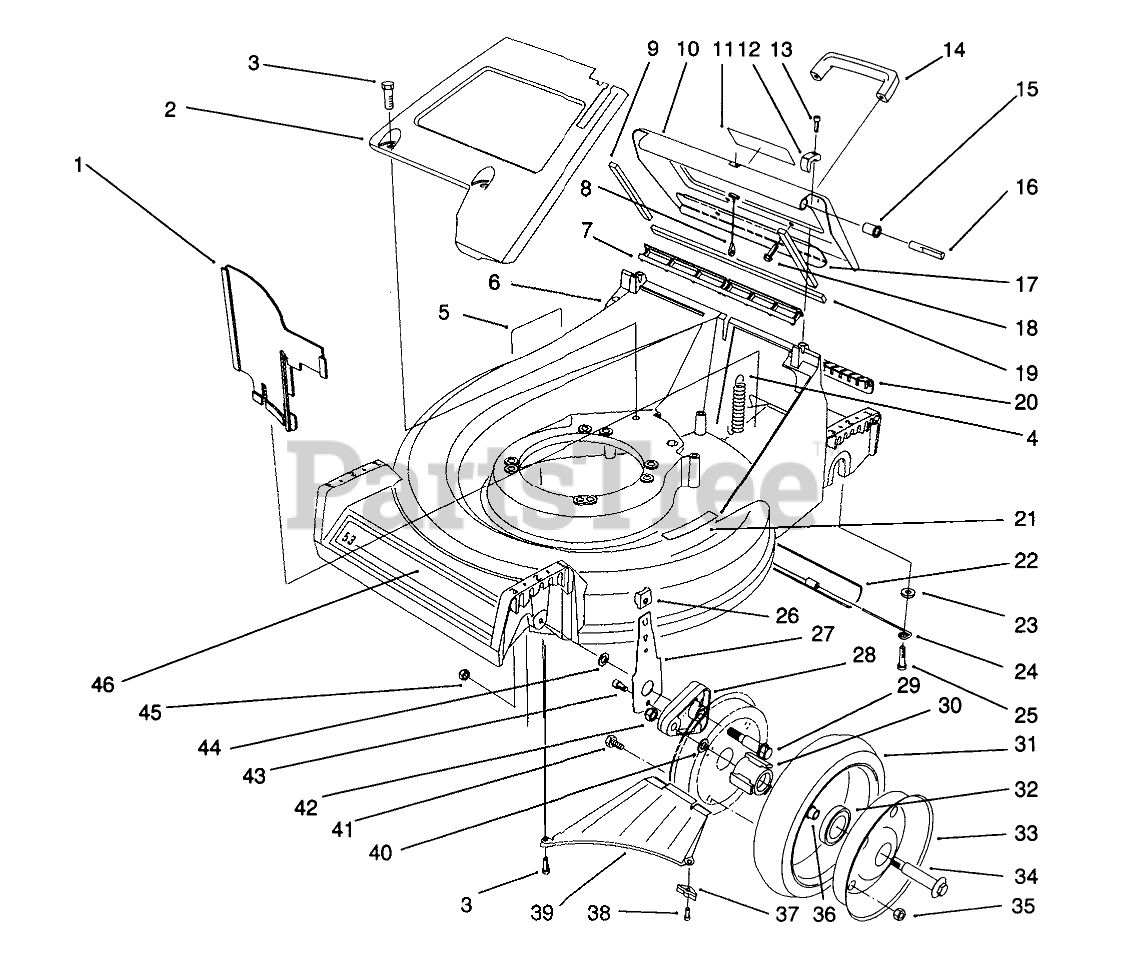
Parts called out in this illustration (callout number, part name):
1	PANEL-VERTICAL
2	PaneI-Screen
3	SCREW-HWHTF
4	EXTENSION-SPRING
5	Decal Danger
6	Housing-53cm (Incl. Ref. #5 & 21)
7	DOOR SEAL
8	DOOR CABLE
9	DOOR SIDE SEAL
10	Door-Discharge (Incl. Ref. #9, 11, 17 & 19)
11	DECAL - DANGER
12	HINGE CLAMP
13	SCREW-HSH
14	HANDLE-DOOR
15	DOOR BUSHING
16	HINGE PIN
17	DOOR - BRACE
18	SCREW-HWH
19	DOOR END SEAL
20	ACCESS COVER
21	DECAL - STEP PAD INT'L
22	TRAILING SHIELD
23	WASHER-PLAIN
24	SHIELD HANGER
25	SCREW-SHOULDER
26	KNOB-ARM
27	FRONT SPRING ARM ASM
28	ARM-PIVOT, FRONT
29	BOLT-SHOULDER
30	HUB-BEARING
32	BEARING-WHEEL
33	Wheel-Half
34	SCREW-HH
35	NUT-LOCK, NI
36	SPACER-BEARING
37	Bracket-Discharge
38	SCREW-HWHTF
39	Ramp Discharge
40	SPACER-WHEEL
41	SCREW-HH
42	NUT-LOCK, NI
43	SCREW-HSH, THREAD FORMING
44	WASHER
45	NUT-LOCK
46	DECAL - 53 CM
